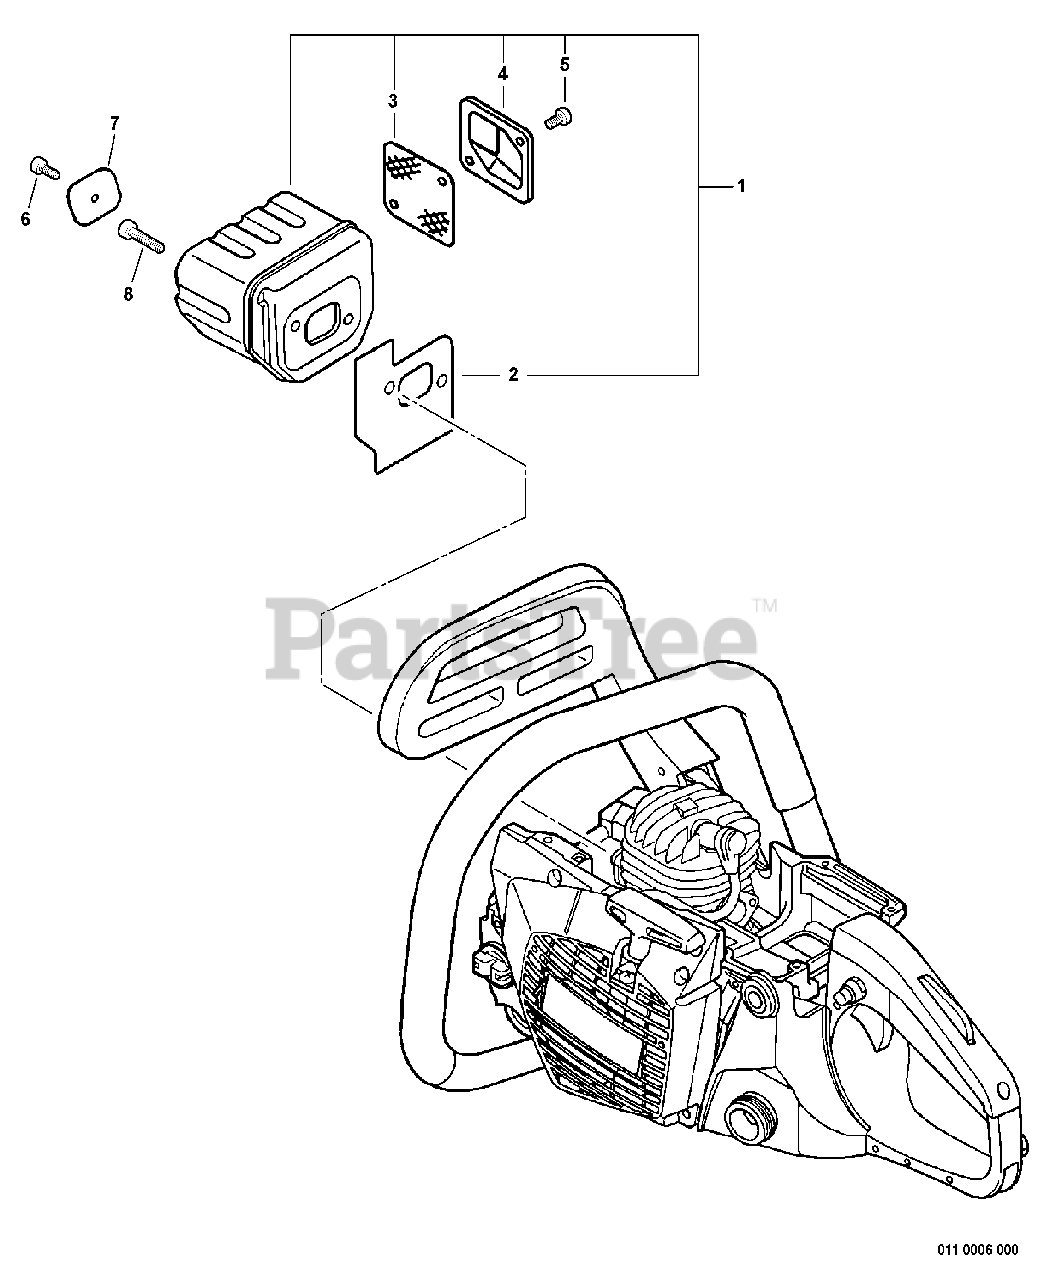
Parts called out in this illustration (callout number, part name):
1	MUFFLER ASSY
2	GASKET, EXHAUST
3	SCREEN, SPARK ARRESTOR
4	GUIDE, EXHAUST
5	SCREW - 4X8
6	SCREW - 4X6
8	SCREW - 5X14
